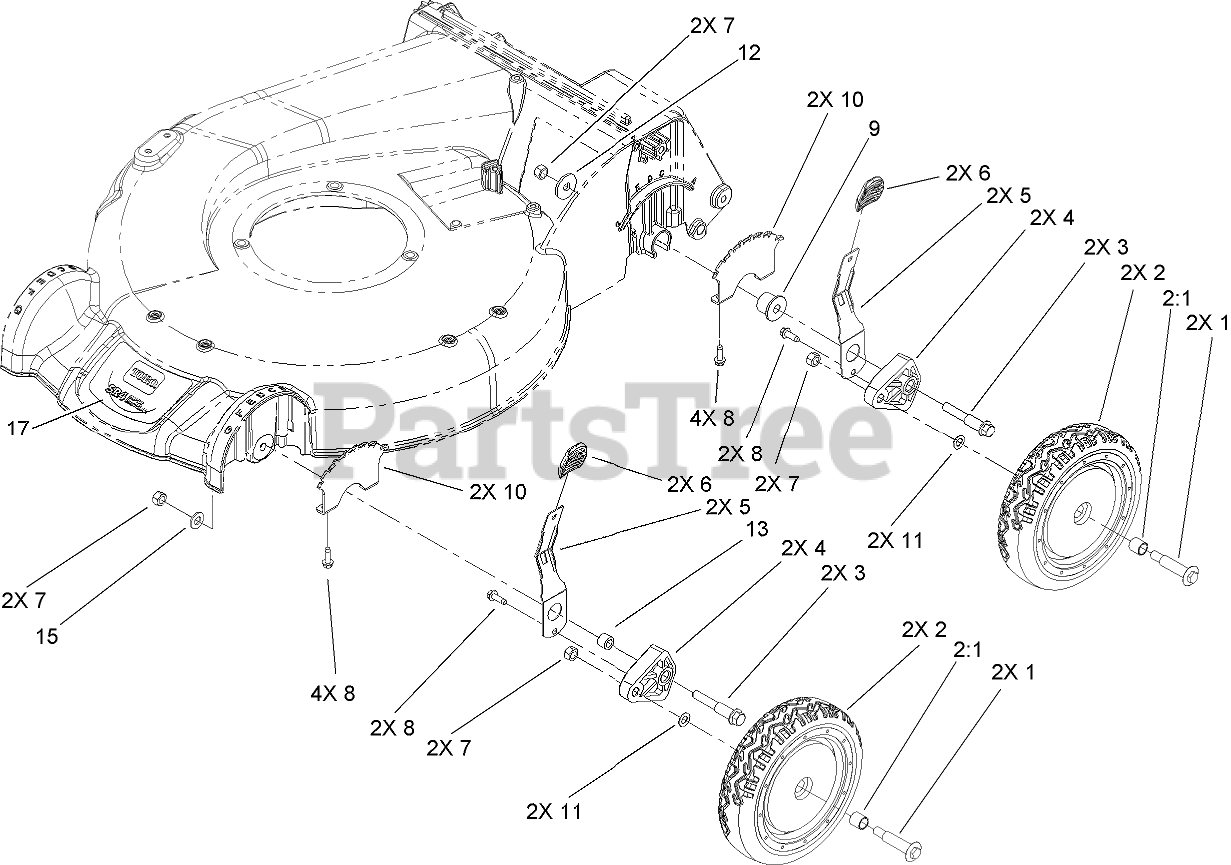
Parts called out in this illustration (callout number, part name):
1	BOLT-SHOULDER
2	WHEEL ASM
2:1	BUSHING
3	SCREW-SHOULDER, HOC
4	ARM-PIVOT
5	ARM-SPRING
6	Knob-Lever, HOC
8	SCREW-HWHTF
9	SPACER-HP
10	PLATE-HOC
11	WASHER
12	WASHER
13	SPACER-WHEEL
15	WASHER-FLAT
17	DECAL-SUPERCARE
